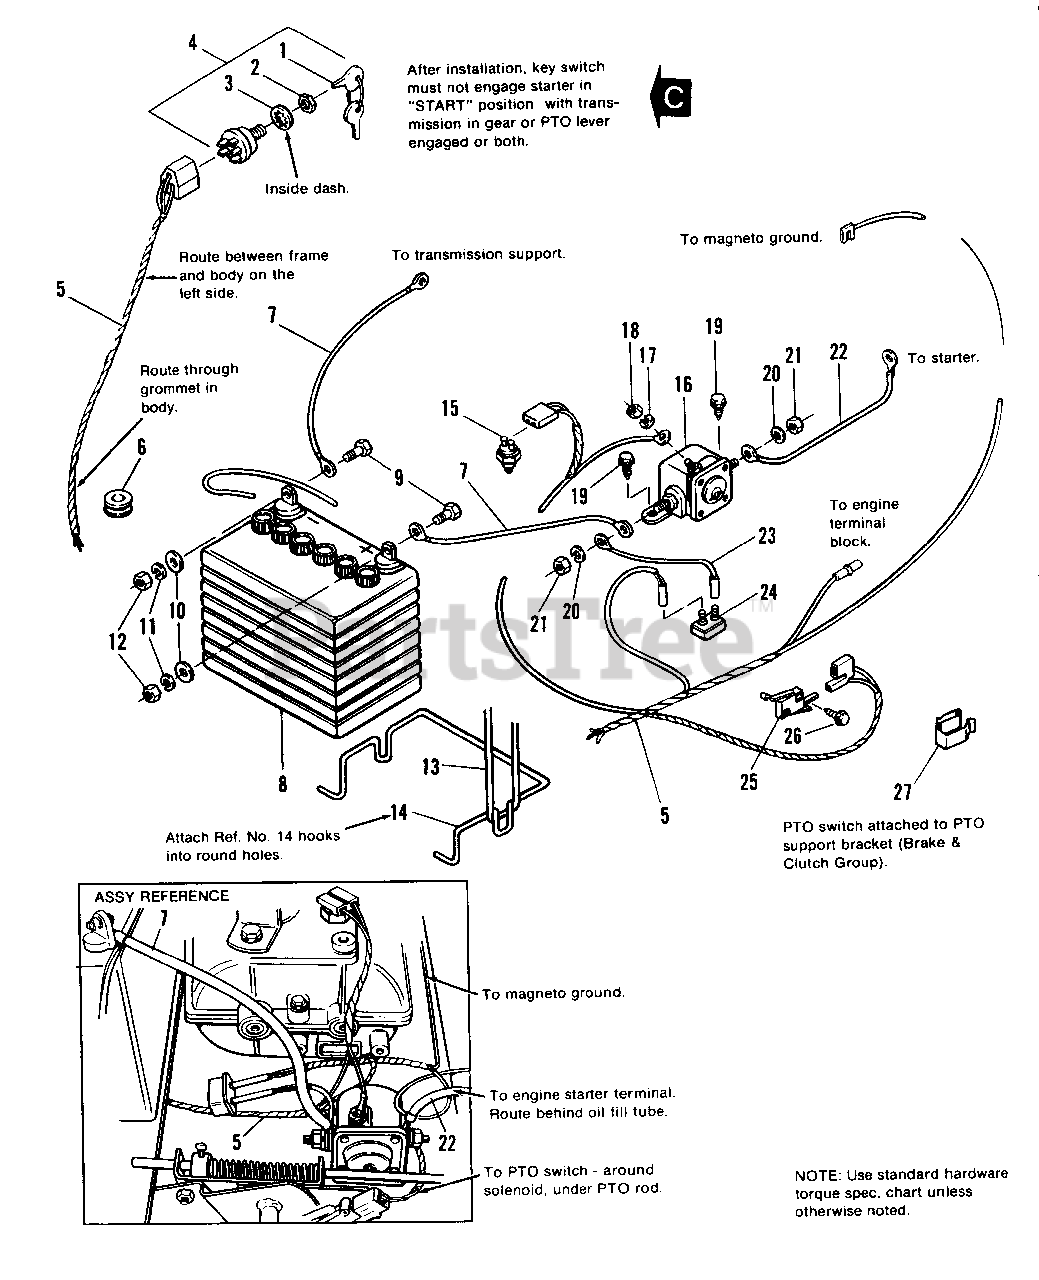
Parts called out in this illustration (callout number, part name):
2	NUT
3	LOCKWASHER, Internal Tooth, 5/8
4	SWITCH, Key
5	HARNESS ASSY.
7	CABLE ASSY.
8	BATTERY, 12 Volt
9	CAPSCREW, Hex, 1/4-20 x 3/4
10	WASHER, Plain, 1/4
11	LOCKWASHER, 1/4
12	NUT, Hex, 1/4-20
13	STRAP, Battery
14	BRACE, Battery
15	SWITCH, Transmission Interlock
17	LOCKWASHER, #10
18	NUT, Hex, Machine, #10-32
19	SCREW, Hex, Taptite, 1/4-20 x 3/8
20	LOCKWASHER, 5/16
21	LOCKNUT, 5/16-18
22	CABLE ASSY. (Solenoid to Starter)
24	BREAKER, Circuit
25	SWITCH, P.T.O. Interlock
26	SCREW, Hex, Taptite, #5-40 x 3/4
27	CLIP, Tinnerman
